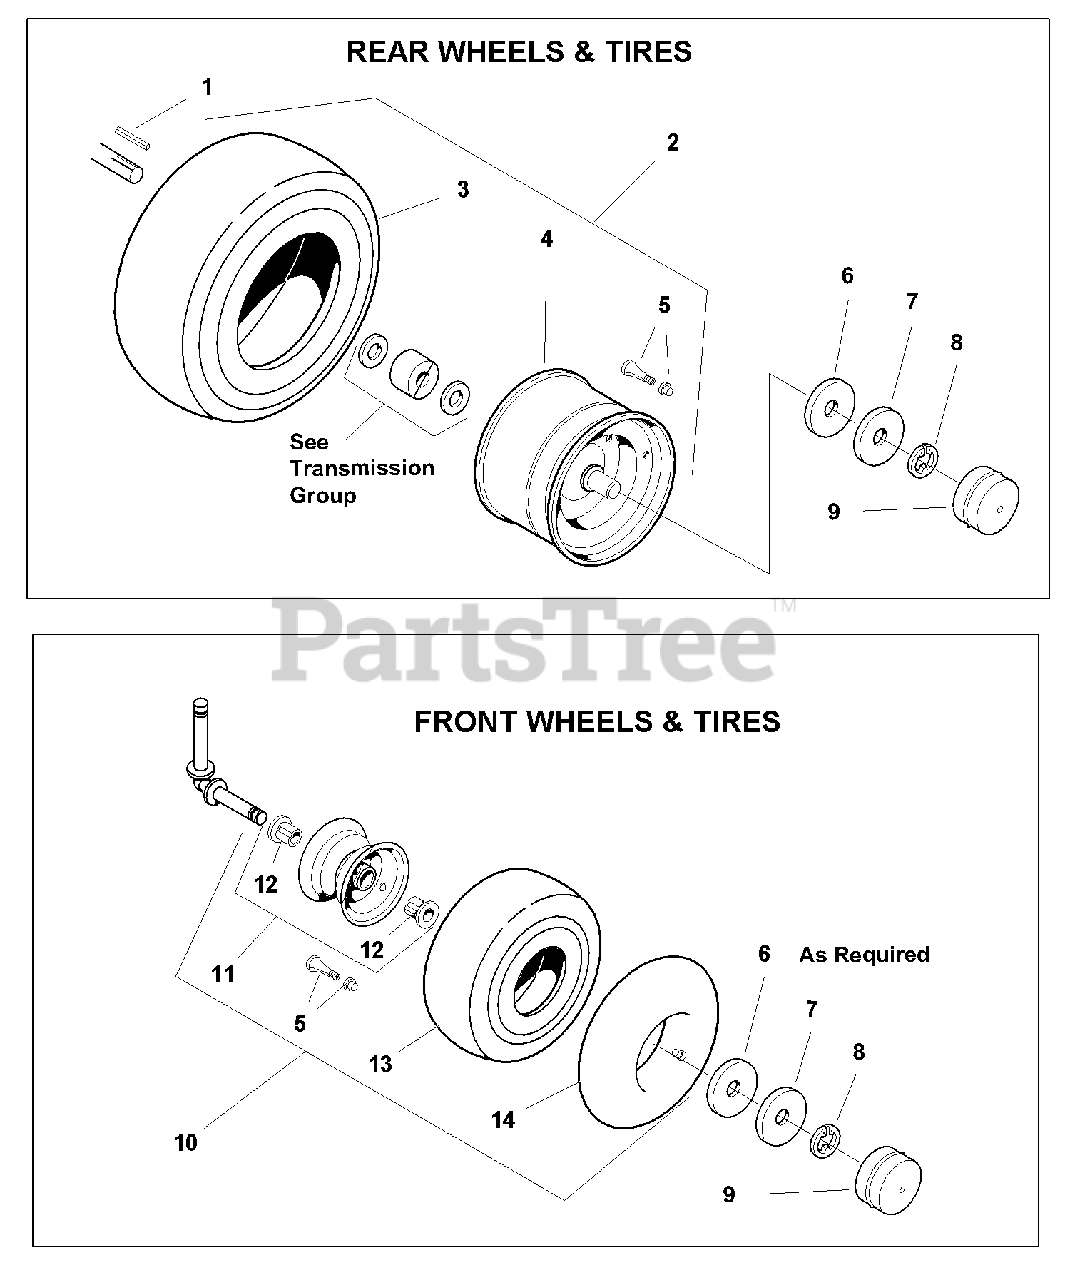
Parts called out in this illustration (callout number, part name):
1	KEY, 3/16 x 2
2	WHEEL & TIRE ASSEMBLY
3	TIRE, 20 x 8 - 8 Super Trac II
4	WHEEL, 7 x 8
5	VALVE STEM & CAP ASSEMBLY
10	WHEEL & TIRE ASSEMBLY (Includes Ref. Nos. 5, 11, 12, 13 & 14)
11	WHEEL & BUSHINGS ASSEMBLY (Includes Ref. No. 12)
12	BEARING
13	TIRE, 15 x 6.5 - 6 Super Trac II
